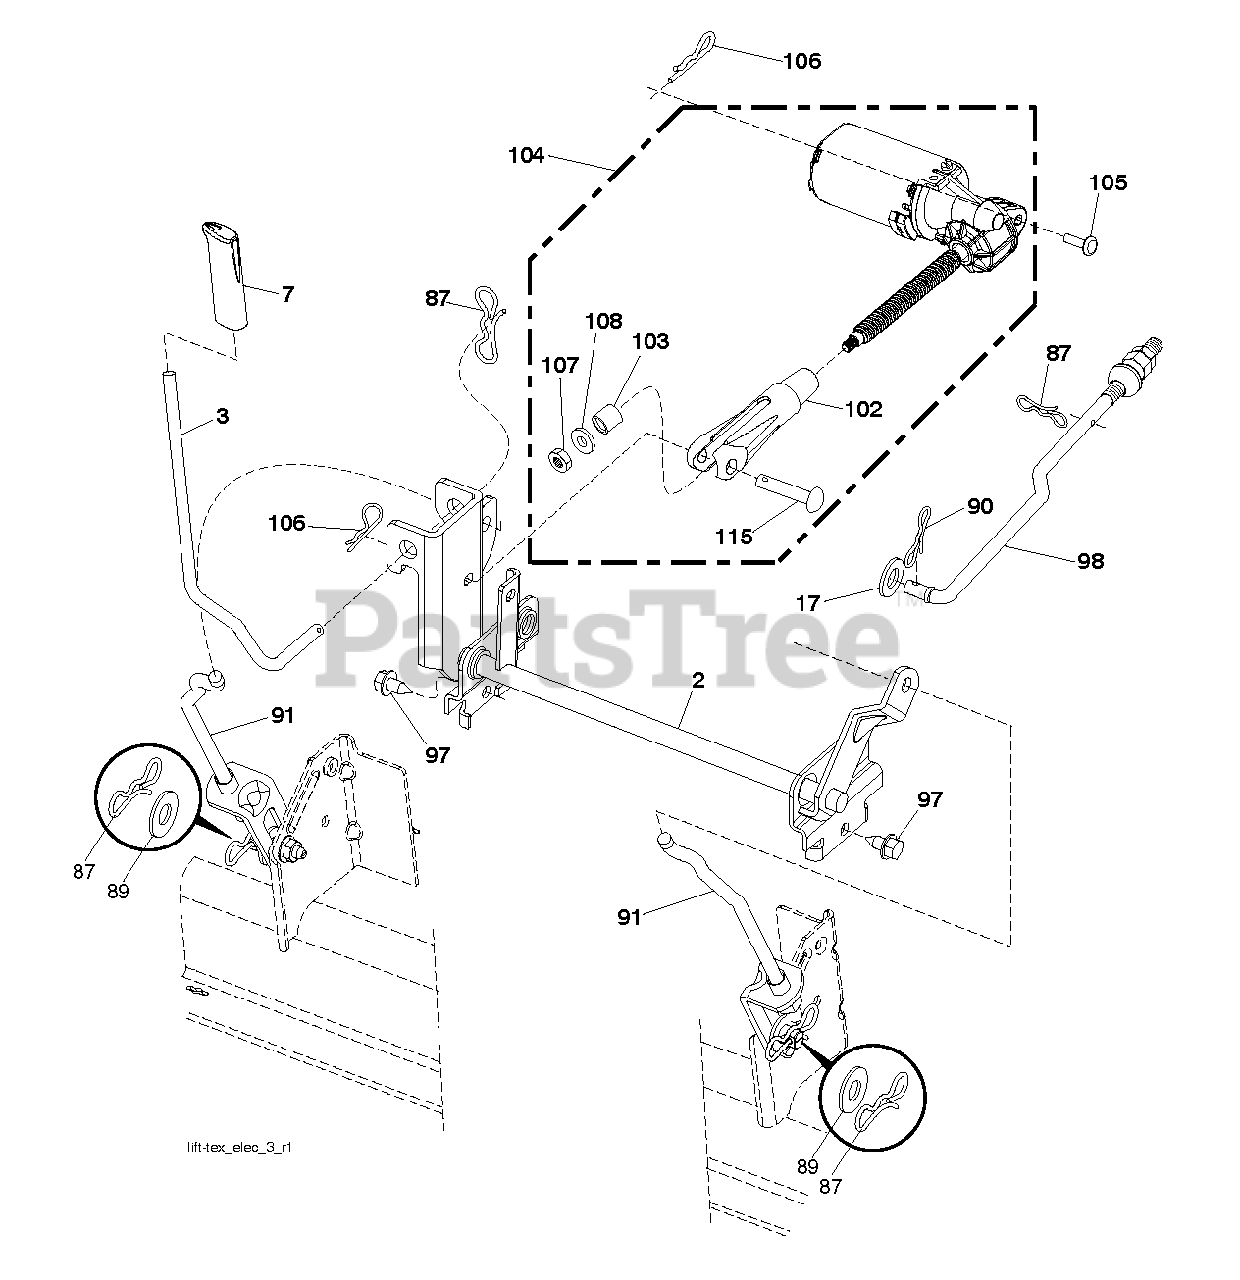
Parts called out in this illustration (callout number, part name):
2	SHAFT.ASM.CROSS.LIFT
3	ROD.INDICATOR.LIFT.ELECTRIC
7	CAP.INDICATOR.LIFT.ELECT.428
17	WASHER
87	PIN.COTTER.7/16.BOW TI.
89	WASHER.CLEAR.ZINC
90	PIN.COTTER.5/16.BOW TI
91	LINK.ASM.LIFT.54"TG
97	SCREW, 3/8-16X3/4
98	LINK.ASM.SUSP.FRONT.MWR.10.5
102	CLEVIS.MOTOR.ELECTRIC
103	SPACER.TUBULAR
104	ACTUATOR.ASM.DECKLIFT.ELECT
105	RIVET,DRILLED
107	NUT.SQ.1/4-20 UNC
115	PIN.CLEVIS.375X2.125
